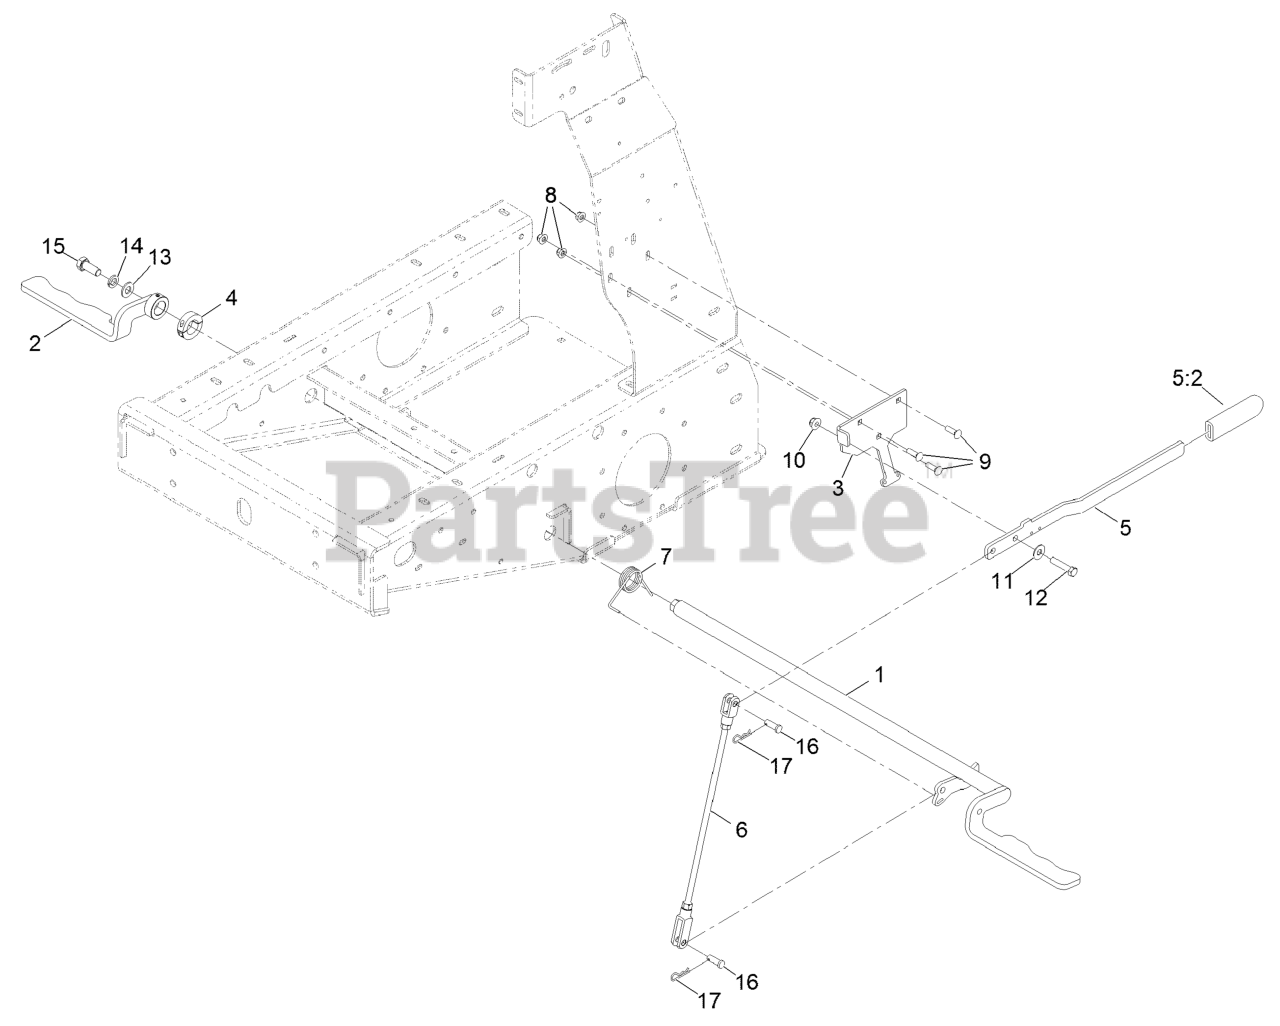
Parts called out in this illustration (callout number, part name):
1	Arm-Brake, Lt [black]
2	Arm-Brake, Rt [black]
3	BRACKET-HANDLE, BRAKE
4	COLLAR-LOCKING
5	ASM, Handle-Brake
5:2	GRIP-LEVER
6	ASM, Rod-Brake
7	SPRING-TORSION
8	Nut-Hex Flange
9	Bolt,Carriage,5/16-18X1,ST/ST 18-8
10	NUT-HF, NI
11	WASHER-FLAT
12	SCREW-HH
13	WASHER-FLAT
14	WASHER-LOCK
15	Screw ( .50-20Unfx1.25 Grade 8]
16	PIN-CLEVIS
17	Pin-Hair
